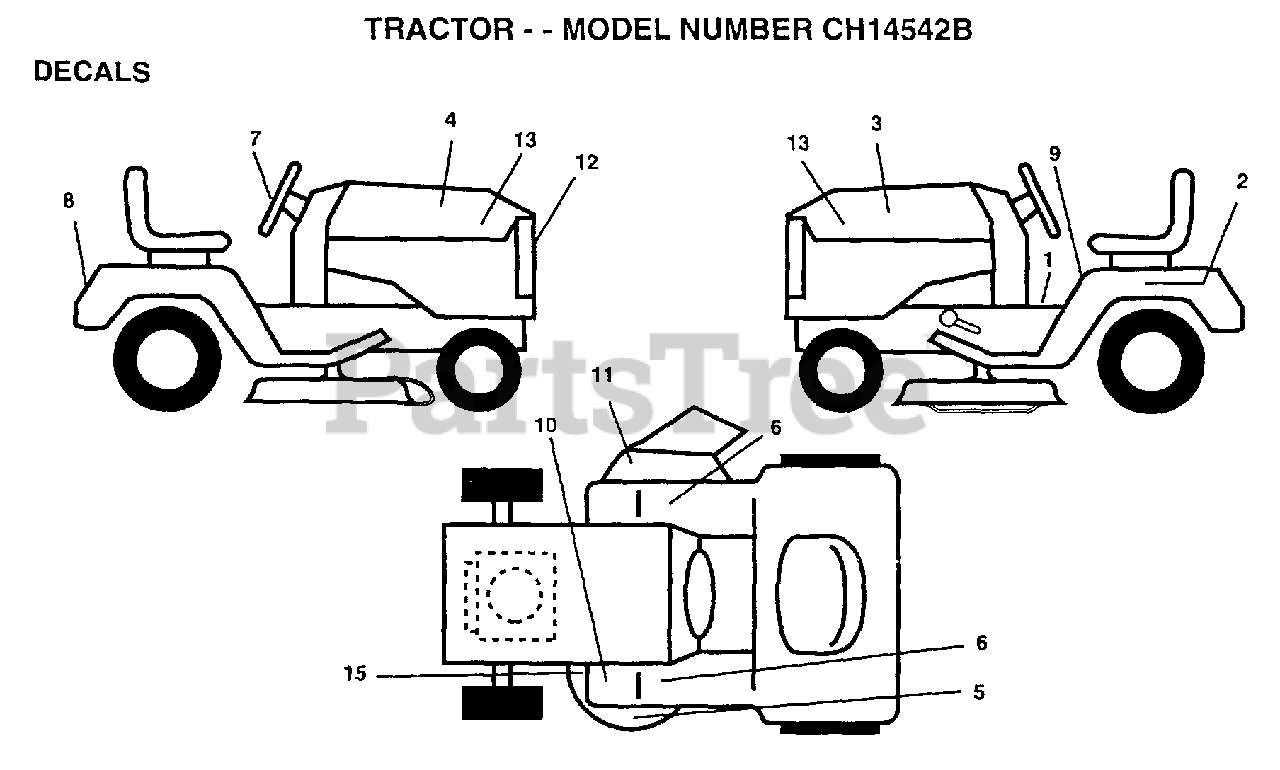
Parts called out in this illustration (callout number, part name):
1	DECAL DASH INS OP
2	DECAL.BTRY.DANGER
3	DECAL. HOOD RH
4	DECAL HOOD LH
5	DECAL.MOWER
6	"PAD,FOOTREST"
7	DECAL.WHL.STRG.
8	DECAL.FENDER
9	DECAL CAUTION
10	DECAL T
11	"DECAL, WARNING"
12	DECAL.GRILL
13	DCL.PNL.SIDE.
15	DECAL
